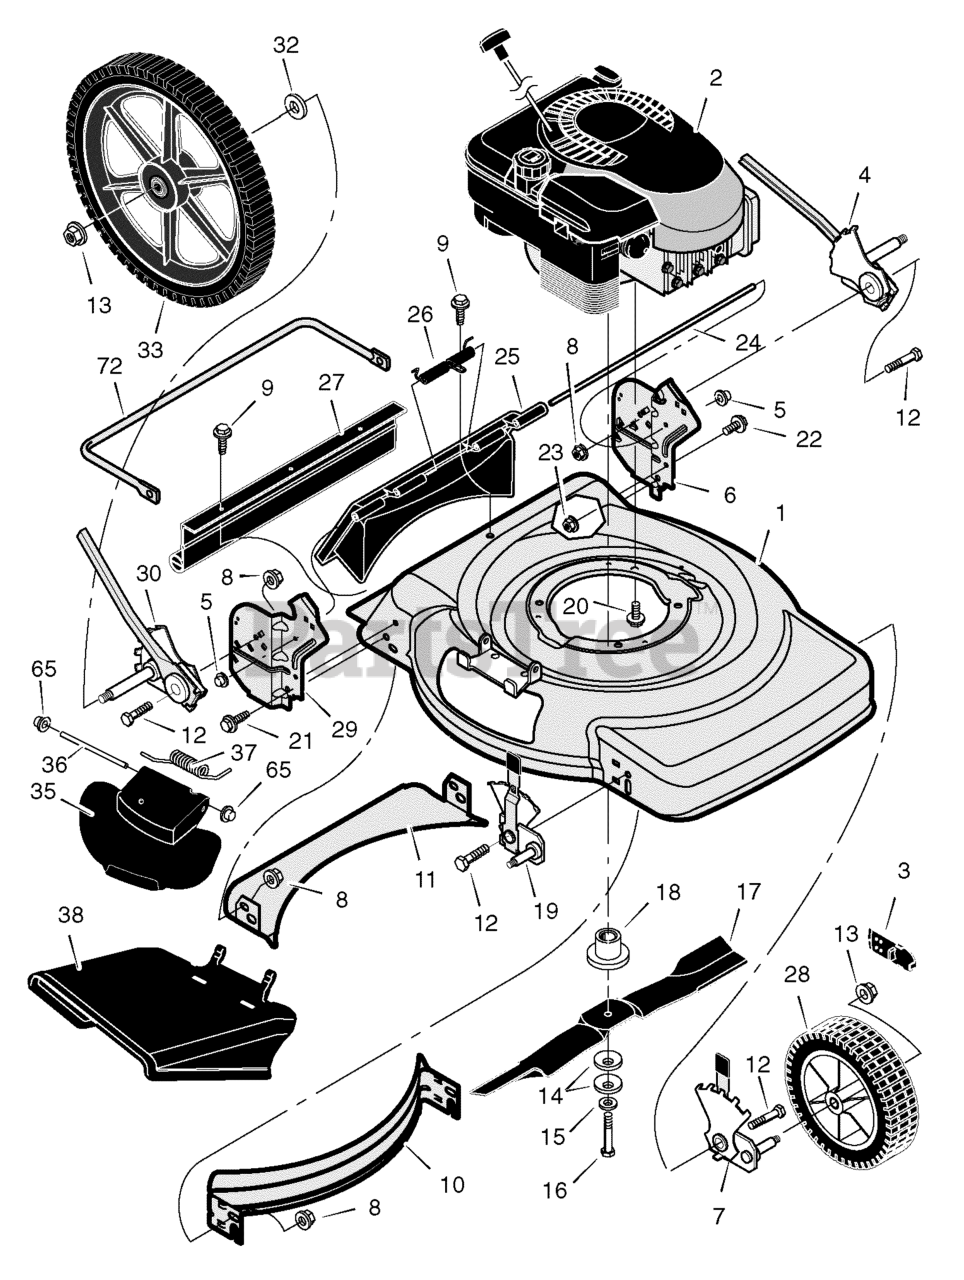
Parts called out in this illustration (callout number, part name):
1	Housing
2	Engine *
3	Cap, Hub (Optional)
4	Adjuster, Left Rear Height
5	Push On Cap
6	Bracket, Left Handle
7	Adjuster, Left Front Height
8	Nut, Flange
10	Baffle, Front
11	Baffle, Rear
13	Nut, Flange
14	Washer, Belleville
15	Washer
18	Adapter, Blade
19	Adjuster, Right Front Height
20	Bolt, Engine
21	Bolt
22	Bolt
23	Nut, Flange
24	Rod, Pivot
25	Door, Rear (Black)
25	Door, Rear (Gray)
26	Spring
27	Guard, Rear
28	Wheel & Tire *
29	Bracket, Right Handle
30	Adjuster, Right Rear Height
32	Washer
33	Wheel, Rear *
35	Cover, Mulch (Black)
35	Cover, Mulch (Gray)
36	Rod, Pivot
37	Spring, Torsion
38	Deflector, Chute (Black)
38	Deflector, Chute (Gray)
65	Push On Cap
